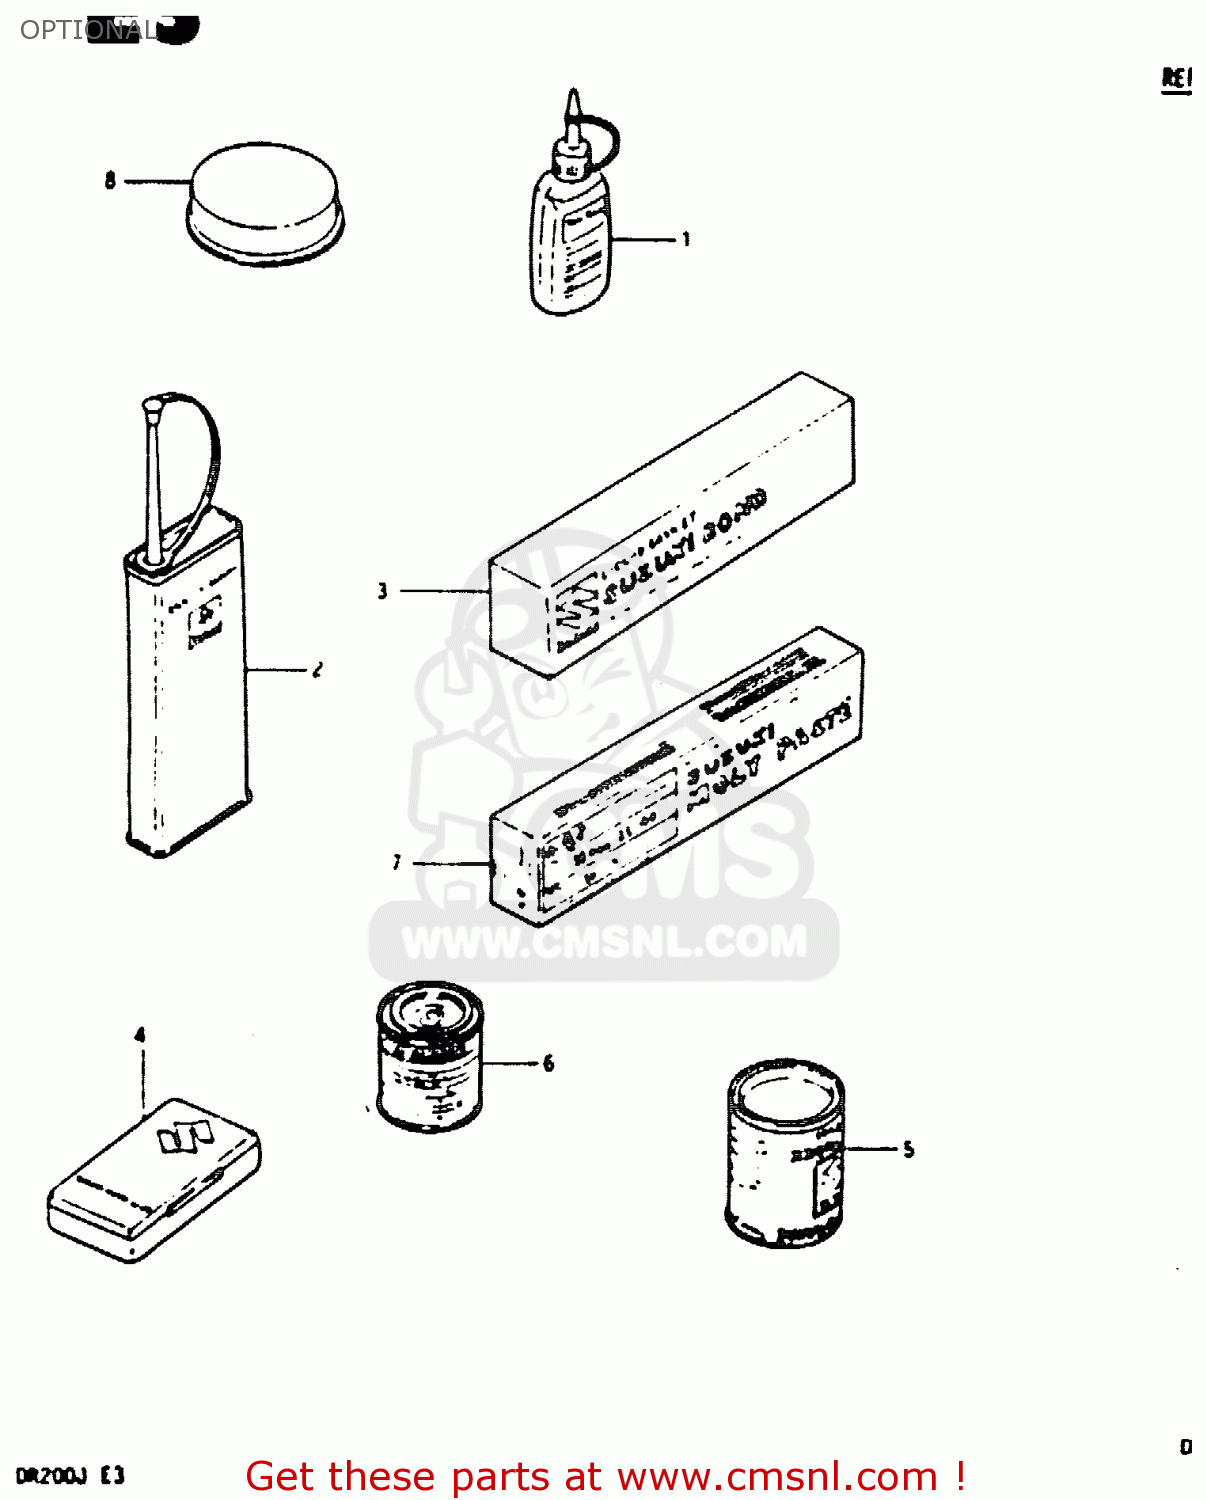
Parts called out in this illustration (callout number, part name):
1	THREAD LOCK SUPER(1360)
2	THREAD LOCK NO.1401 CLEAR 200G
3	LIQUID GSKT NO.1207B 100G BLK
4	TUBE REPARING TOOL
5	GREASE(C)EP2 LITHIUM 150G
6	PAINT,BLACK
7	SUZUKI MOLY PASTE
8	GREASE,PBC FOR BRK PAD 20G
